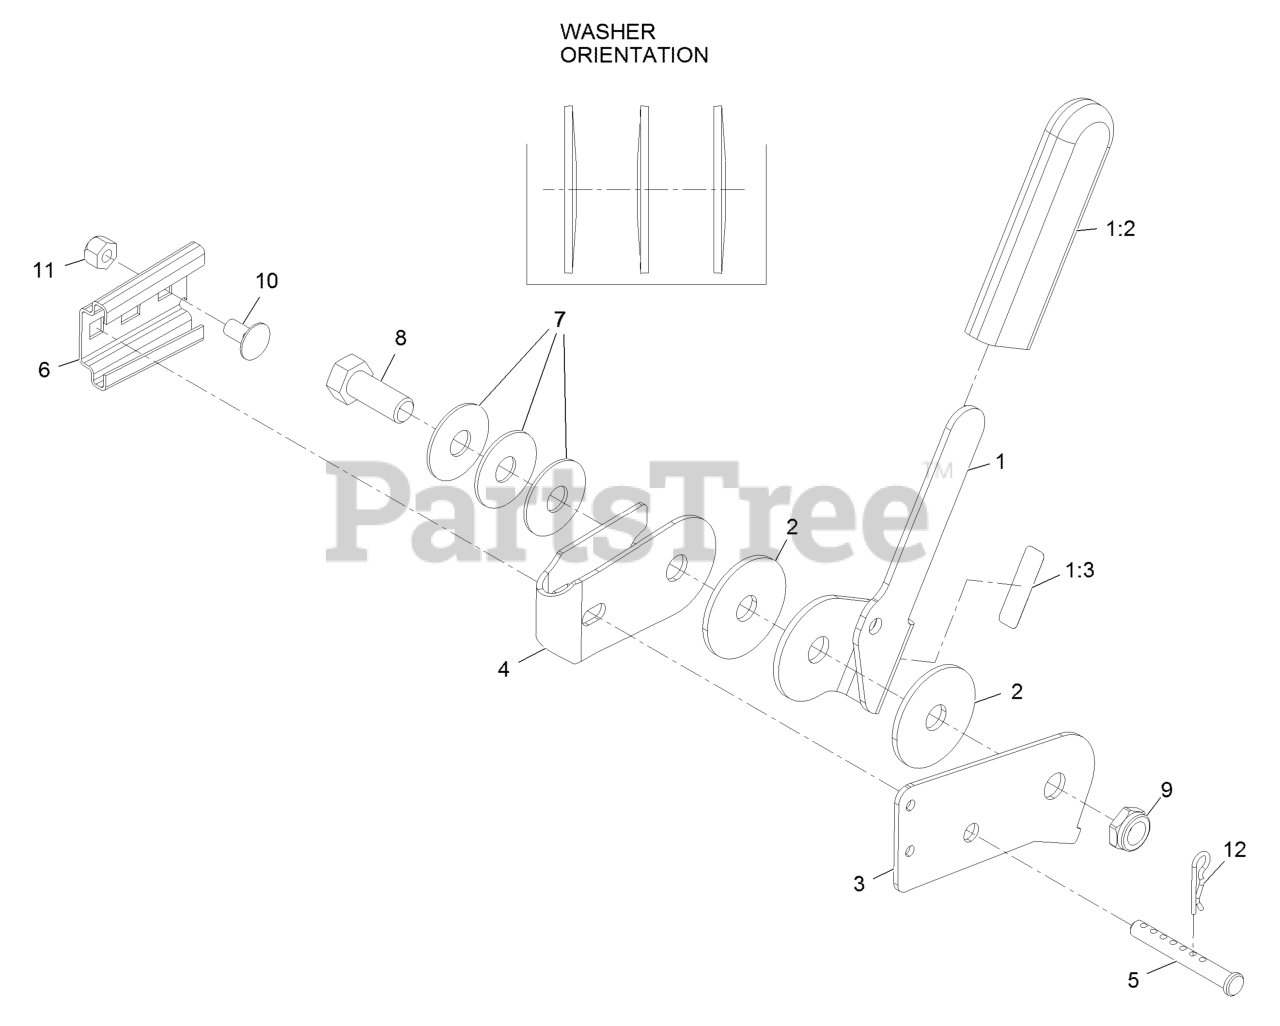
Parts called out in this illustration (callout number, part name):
1	CONTROL HANDLE ASM-OCD
1:2	GRIP-LEVER
1:3	DECAL,OPERATION
2	DISC-FRICTION
3	BRACKET,CONTROL MOUNT
4	BRACKET,HANDLE MOUNT
5	PIN-CLEVIS
6	BRACKET-MOUNTING,SMV
7	WASHER-DISC, SPRING
8	SCREW-HH
9	NUT-HEX
10	SCREW-CARR
11	NUT-LOCK, NI
12	PIN-COTTER
